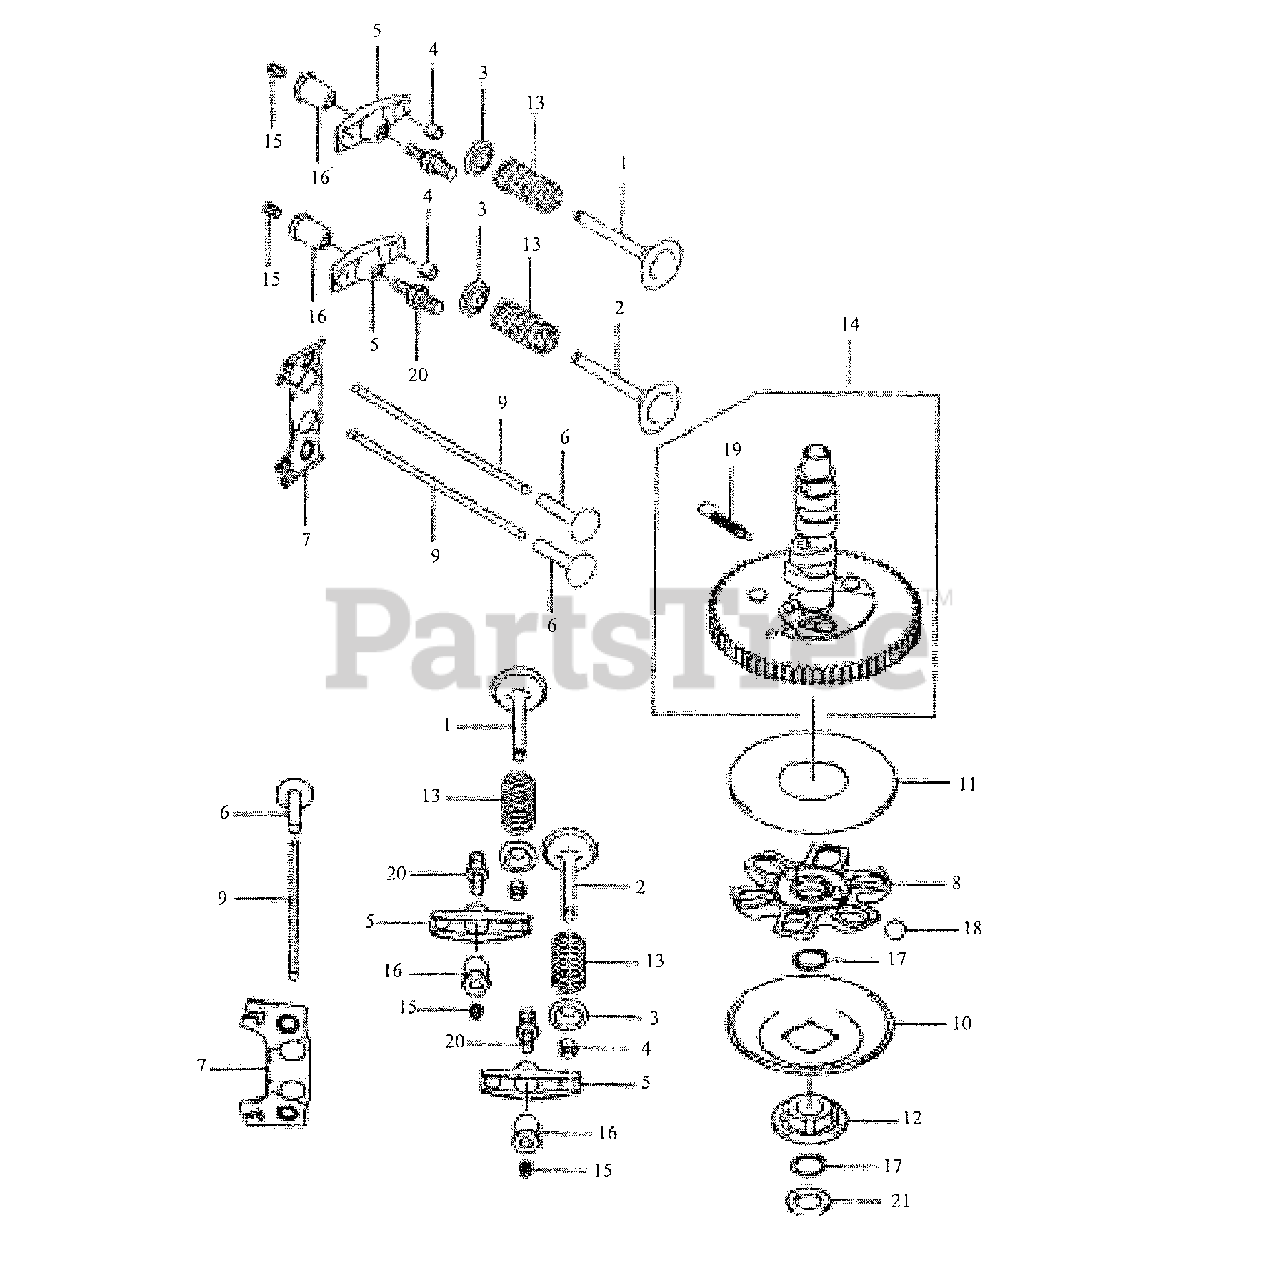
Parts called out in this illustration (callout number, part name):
2	Valve-Exhaust
3	Retainer, Valve Spring
5	Arm-Rocker
7	Guide, Push Rod
10	Plate
12	Sleeve
13	Spring-Engine Valve
14	Camshaft-Complete
17	Ring-Snap
18	Ball
19	Spring
20	Bolt
